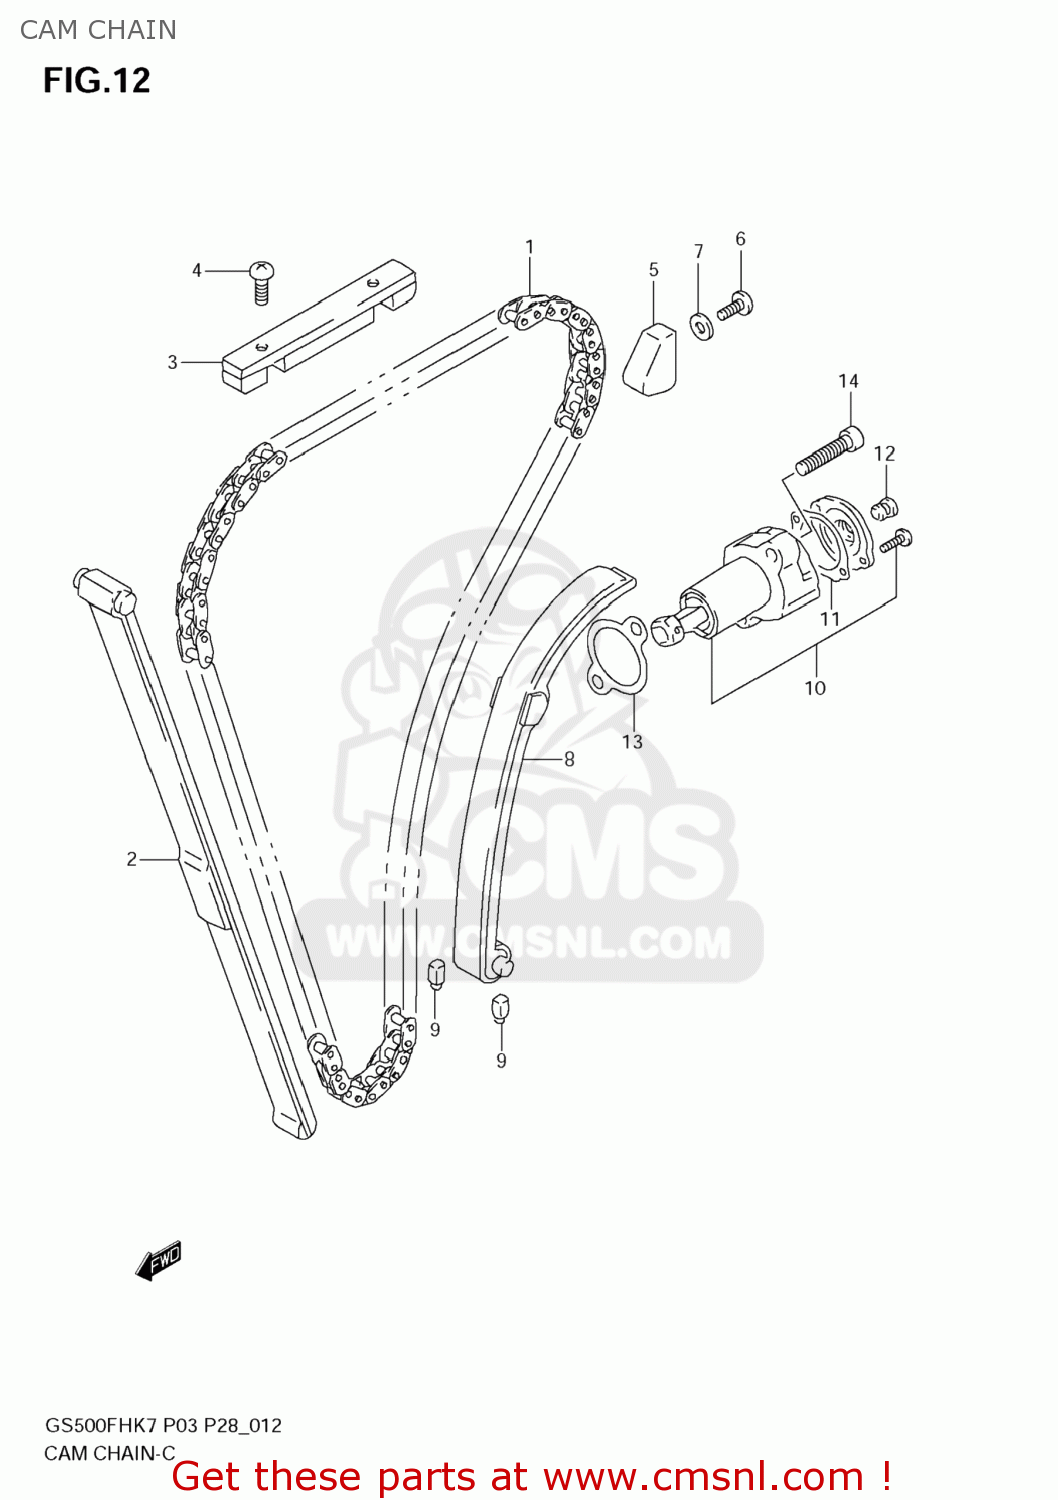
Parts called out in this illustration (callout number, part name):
1	CHAIN,CAMSHAFT DRIVE(120L)
2	GUIDE,CAM CHAIN NO.1
3	GUIDE,CAM CHAIN
4	SCREW
5	GUIDE,CAM CHAIN
6	BOLT
7	GASKET(5.8X13X1.2) (NAS)
8	TENSIONER,CAM CHAIN
9	CUSHION,CAM CHAIN TENSIONER
10	ADJUSTER ASSY,TENSIONER
11	GASKET,ADJUSTER CAP (NAS)
12	PLUG,ADJUSTER
13	GASKET,TENSIONER ADJUSTER (NAS)
14	BOLT
